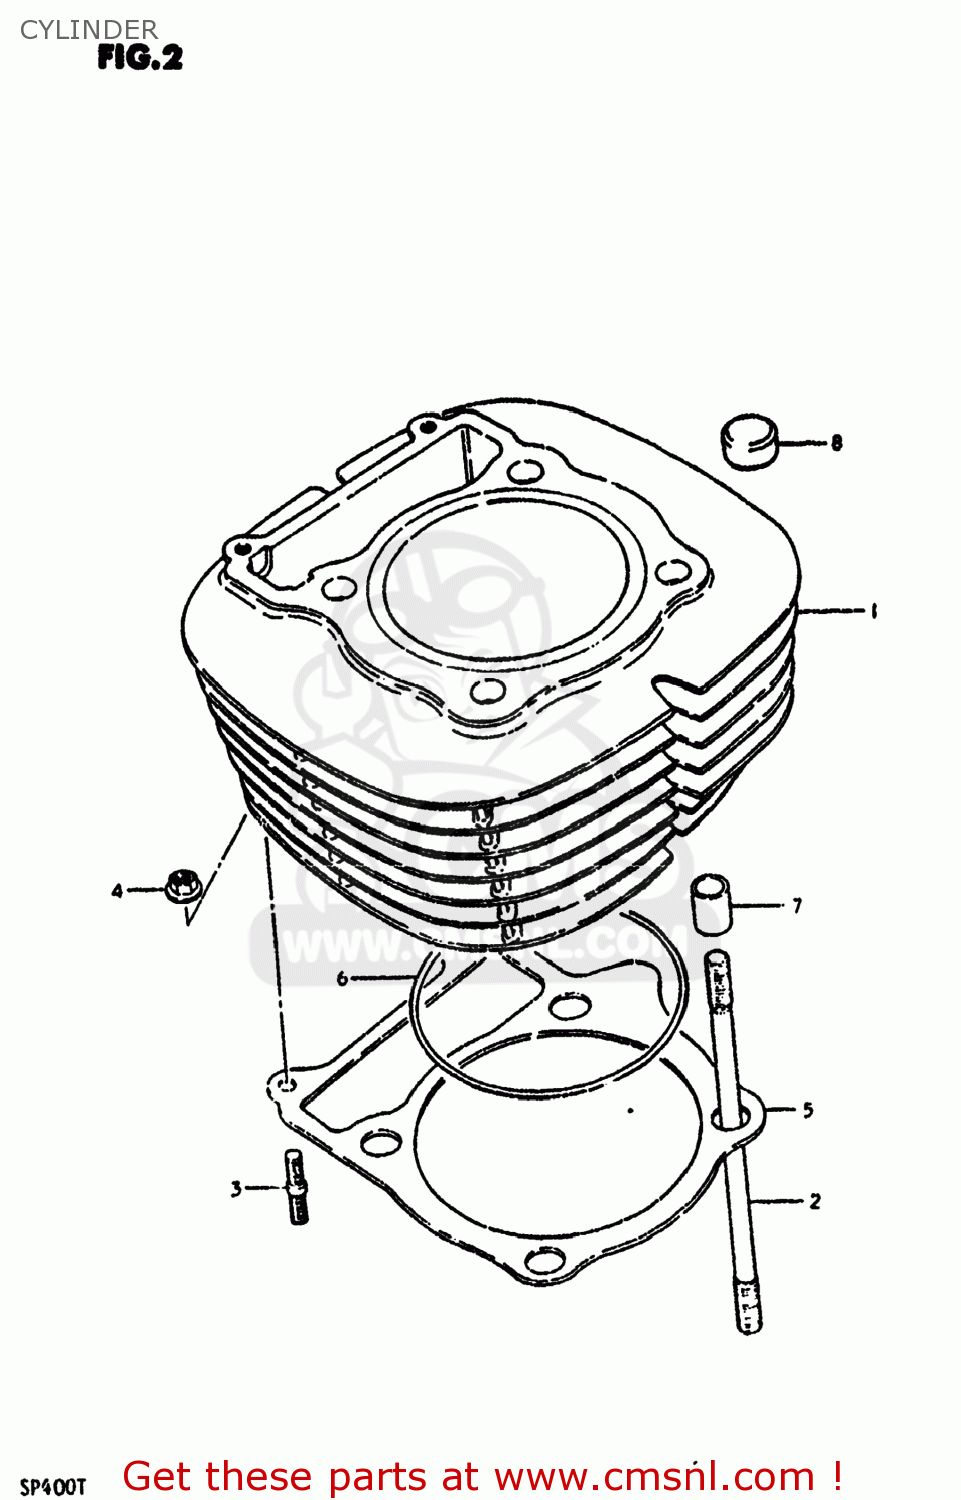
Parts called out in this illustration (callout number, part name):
1	CYLINDER
2	STUD
3	STUD 6X20
4	NUT
5	GASKET,CYLINDER (MCA)
6	O RING(D:2,ID:87)
7	PIN
8	PAD,CYLINDER HEAD
